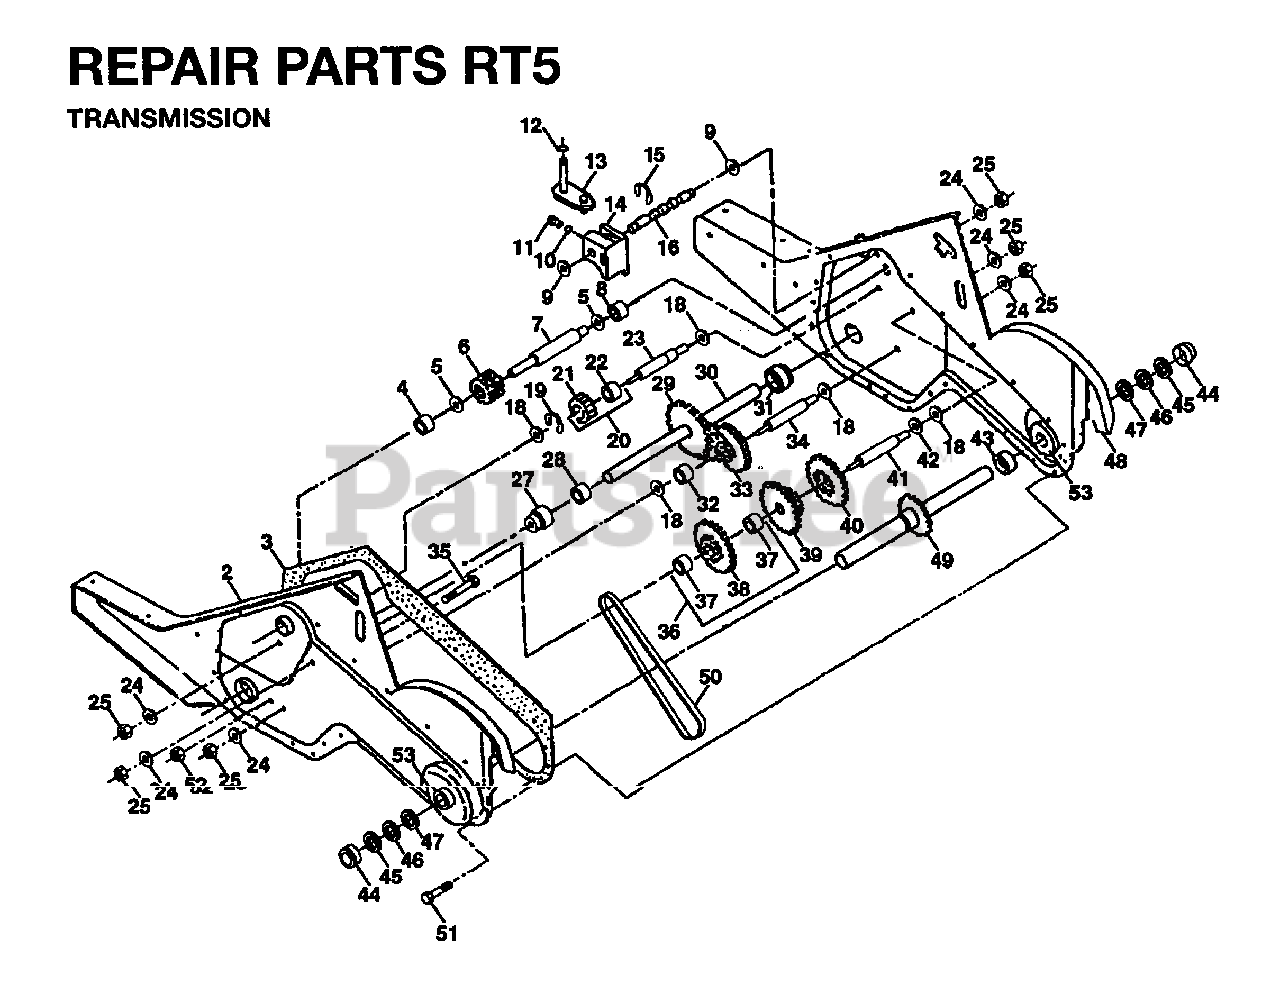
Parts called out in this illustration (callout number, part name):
1	TRANSMISSION ASSY
2	GEARCASE L.H.
3	GASKET TI
4	NEEDLE BRNG LT
5	THRUST WASHER
6	GEAR.PINION.INPUT
7	SHAFT-INPUT CRT
8	BEARING TI
9	WASHER SEAL CRT
10	STEEL BALL KIT
11	SPRING-SHIFT CRT
12	O-RING TI
13	SHIFTING ARM
14	SHIFT FORK TI
15	KLIP RING
16	SHIFT SHAFT
19	KLIP RING
20	GEAR ASSY CRT
21	GEAR-REV IDLR CRT
22	NEEDLE BEARING TI
23	SHAFT CRT
24	LOCKWASHER
27	BEARING, SHAFT LH CRT
29	CHAIN CRT
30	SHAFT ASSY
31	BEARING, SHAFT RH CRT
32	SPACER TI
33	SPRCKT 8 GEAR CRT
34	SHAFT.SECONDARY.REDUCTION.CRT
35	SCRW WHIZ LOK CRT
36	SPROCKET ASSY W/ BRG
37	BEARING
38	SPROCKET ASSY W/ BRG
39	GEAR TI
41	SHAFT.REDUCTION.TILLER
42	BRNG RACE T
43	SPACER TI
44	CUP
45	RING SPIRAL CRT
47	OIL SEAL STD
48	GEARCASE R.H.
49	TINE SHAFT
50	CHAIN.TILLER
51	BOLT
53	BEARING KIT
